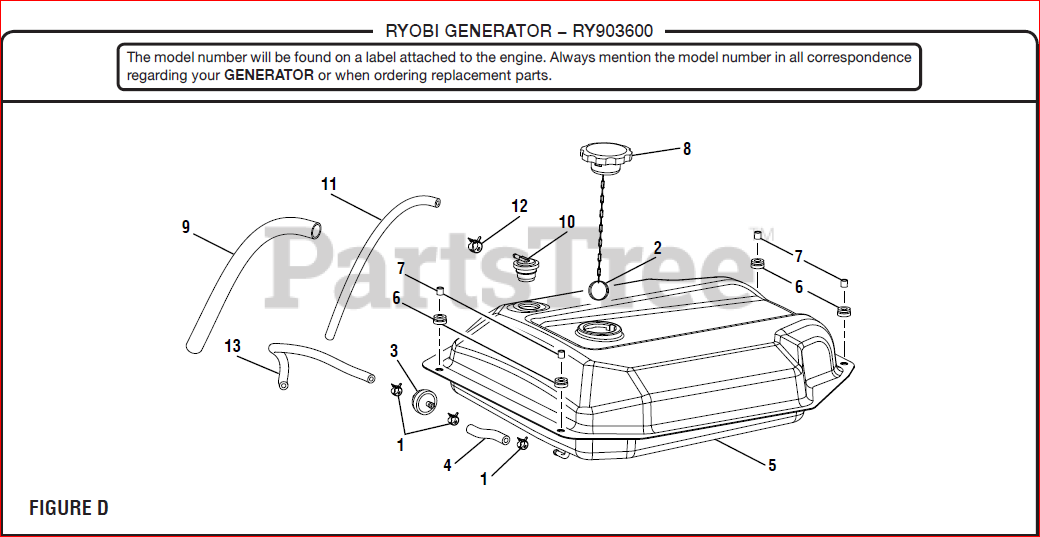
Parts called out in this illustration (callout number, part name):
1	Fuel Line Clamp (1/2 in.).
2	Ring Clip
3	Fuel Filter Inline (1/4 in.)
4	Fuel Hose (80 mm)
5	Fuel Tank
6	Spacer (Fuel Tank Isolator)
7	Bushing (Fuel Tank Isolator)
8	Fuel Cap Assembly
9	Fuel Hose Cover (200 mm)
10	Fuel Tank Vent Valve (PS905055SA)
11	VAPOR HOSE, 630MM X 5ID/8ID
12	Fuel Line Clamp (7/16 in., BM903611)
13	Fuel Hose (300 mm)
